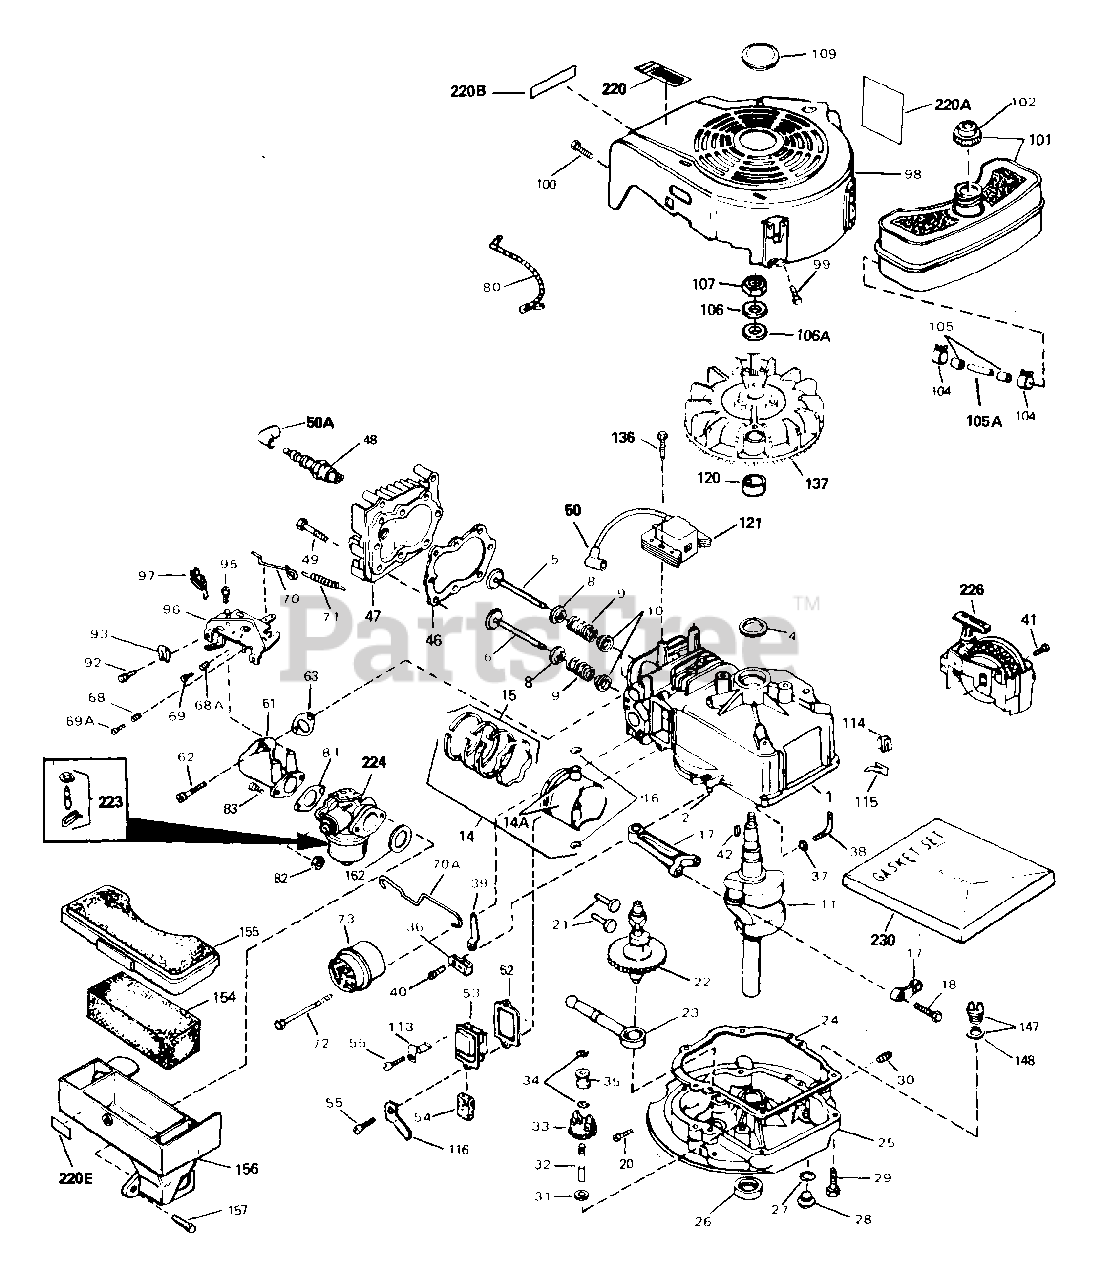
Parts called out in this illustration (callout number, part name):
1	"Cylinder Assy. (2-1/2" Bore)
2	Pin, Dowel
4	Seal, Oil
5	Valve, Intake (Std.)
5	Valve, Intake (1/32" oversize)
6	Valve, Exhaust (Std.)
6	Valve, Exhaust (1/32" oversize)
8	Cap, Upper valve spring (Intake)
9	Spring, Valve
10	Cap, Lower valve spring
11	Crankshaft Assy.
14	Piston, Pin & Ring Assy. (Std.) (2-1/ 2")
14	Piston, Pin & Ring Assy. (.010 oversi ze)
14	Piston, Pin & Ring Assy. (.020 oversi ze)
14A	Piston & Pin Assy. (Std.) (2-1/2")
14A	Piston & Pin Assy. (.010 oversize)
14A	Piston & Pin Assy. (.020 oversize)
15	Ring Set, Piston (Std.) (2-1/2")
15	Ring Set, Piston (.010 oversize)
15	Ring Set, Piston (.020 oversize)
16	Ring, Piston pin retaining
17	Rod Assy., Connecting
18	Bolt, Connecting rod
21	Lifter, Valve
22	Camshaft (Compression Release)
23	Oil Pump Assy.
24	Gasket, Mounting flange
25	Flange Assy., Mounting
26	Seal, Oil
27	Gasket, Oil drain plug
28	Plug, Oil drain
29	Screw, Hex. hd. Sems, 1/4-20 x 1-1/4
31	Washer, Flat
32	Shaft, Mechanical governor
33	Gear Assy., Governor
34	Ring, Retaining
35	Spool, Governor
36	Clamp, Governor lever
37	Washer, Flat
38	Rod, Governor
39	Lever, Governor
40	Screw, Hex washer hd., 8-32 x 5/16
41	Screw, Hex washer hd. taptite, 1/4-20 x 5/8
42	Key, Flywheel (External, point igniti on)
46	Gasket, Head
47	Head, Cylinder
48	Resistor Spark Plug (7/1/91)
49	Screw, Hex flange hd., 5/16-18 x 1-1/ 2
49	Screw, Hex flange hd., 5/16-18 x 2-1/ 2
52	Gasket, Breather
53	Breather Assy.
54	Element, Breather
55	Screw, Hex hd. Sems, 10-24 x 1/2
61	Pipe, Intake
62	Screw, Hex hd. Sems, 1/4-20 x 1
63	Gasket, Intake
68	Spring, Torsion
68A	Spring, Torsion
69	Screw, Fil hd. 5-40 x 7/16
69A	Screw, Fil. hd. 6-32 x 21/32
70	Link, Governor spring
70A	Link, Governor-to-throttle
71	Spring, Governor
72	Screw, Hex hd., 1/4-20 x 2-3/8
72	Screw, Hex hd., 1/4-20 x 2-1/4
72	Screw, Hex hd., 1/4-20 x 2-3/4
72	Screw, Hex hd., 1/4-20 x 2-1/2
73	Muffler Kit
80	Wire, Ground (Two female fittings & o ne
81	Gasket, Carburetor
82	Nut & Lockwasher Assy., 1/4-28
83	Screw, Hex hd., 1/4-28 x 7/8
95	Screw, Hex washer hd. self-tap Sems, 10-24 x
97	Terminal Assy.
98	Housing, Blower
99	Screw, Hex washer hd. Powerlok thread ,
100	Screw, Hex washer hd. self-tap Sems, 10-24 x
102	Cap, Fuel filler (Red Plastic) (Spurt
104	Clamp, Fuel line
105	Line, Fuel (Braided 8-1/4"
105	Line, Fuel (Braided 16")
105	Line, Fuel (Braided 32")
105	Line, Fuel (Epichlorohydrin 6-3/4")
106	Washer, Belleville
107	Nut, Flywheel
109	Plug, Screen
113	Clip, Magneto wire
121	Lamination & Coil Assy.
121	Magneto-to-Solid State Conversion Kit
136	Screw, Torx Hex washer hd. Sems, 10-2 4 x 1
137	Flywheel
220A	Decal, Instruction (Bilingual)
223	Inlet Needle, Seat & Clip Assy.
224	Carburetor
226	Starter, Side mount rewind
230	Gasket Set
